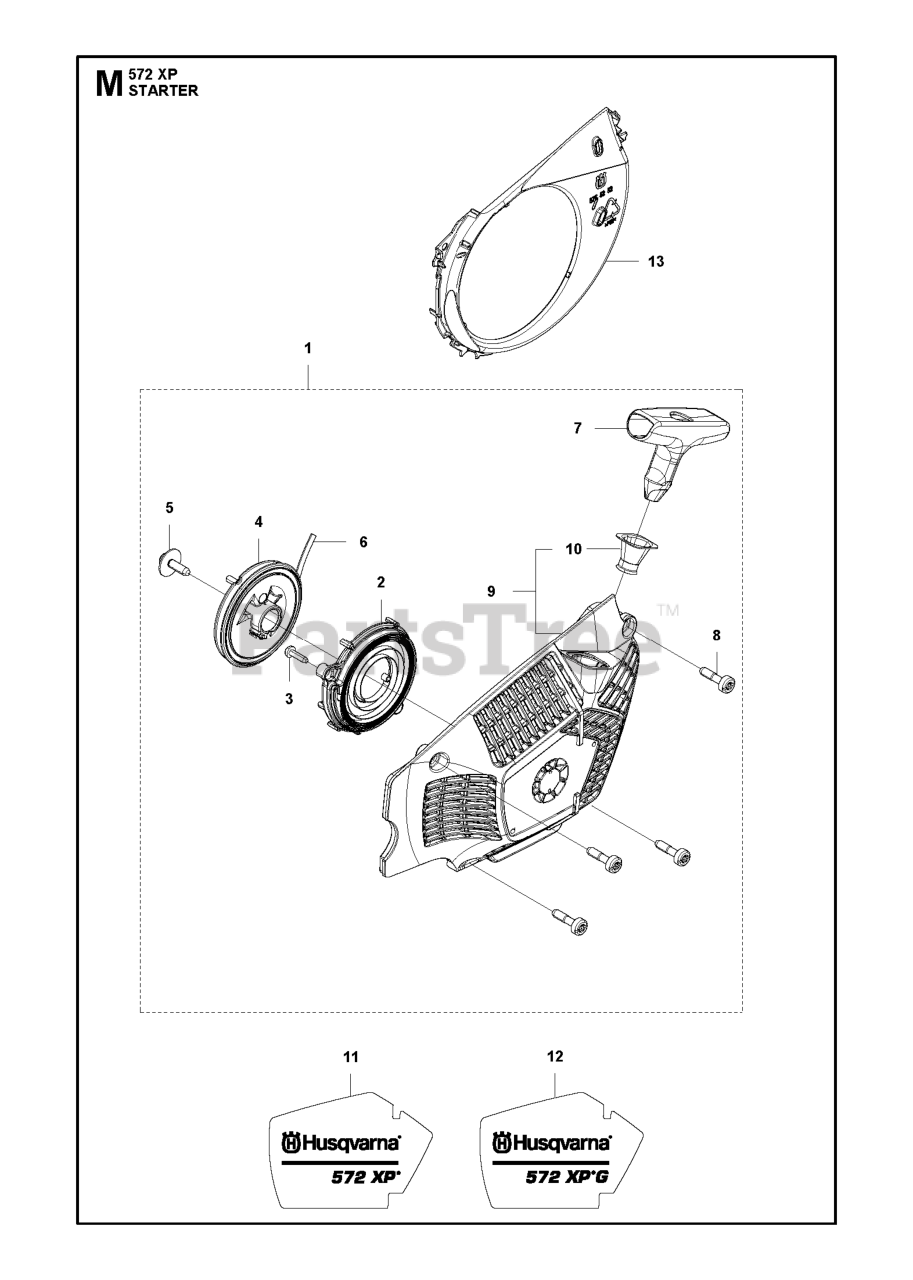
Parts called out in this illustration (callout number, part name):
1	STARTER HOUSING H565/H572 WITH
2	SPRING CASSETTE ADDY
3	SCREW CITXPANT
4	STARTER PULLEY ASSY
5	SCREW ITXSCT MT5X16 10.9 TBO
6	STARTER ROPE
8	SCREW CITXPANMO
9	STARTER HOUSING
11	DECAL STARTER 572XP
12	DECAL STARTER 572XPG
13	BAFFLE AIR
